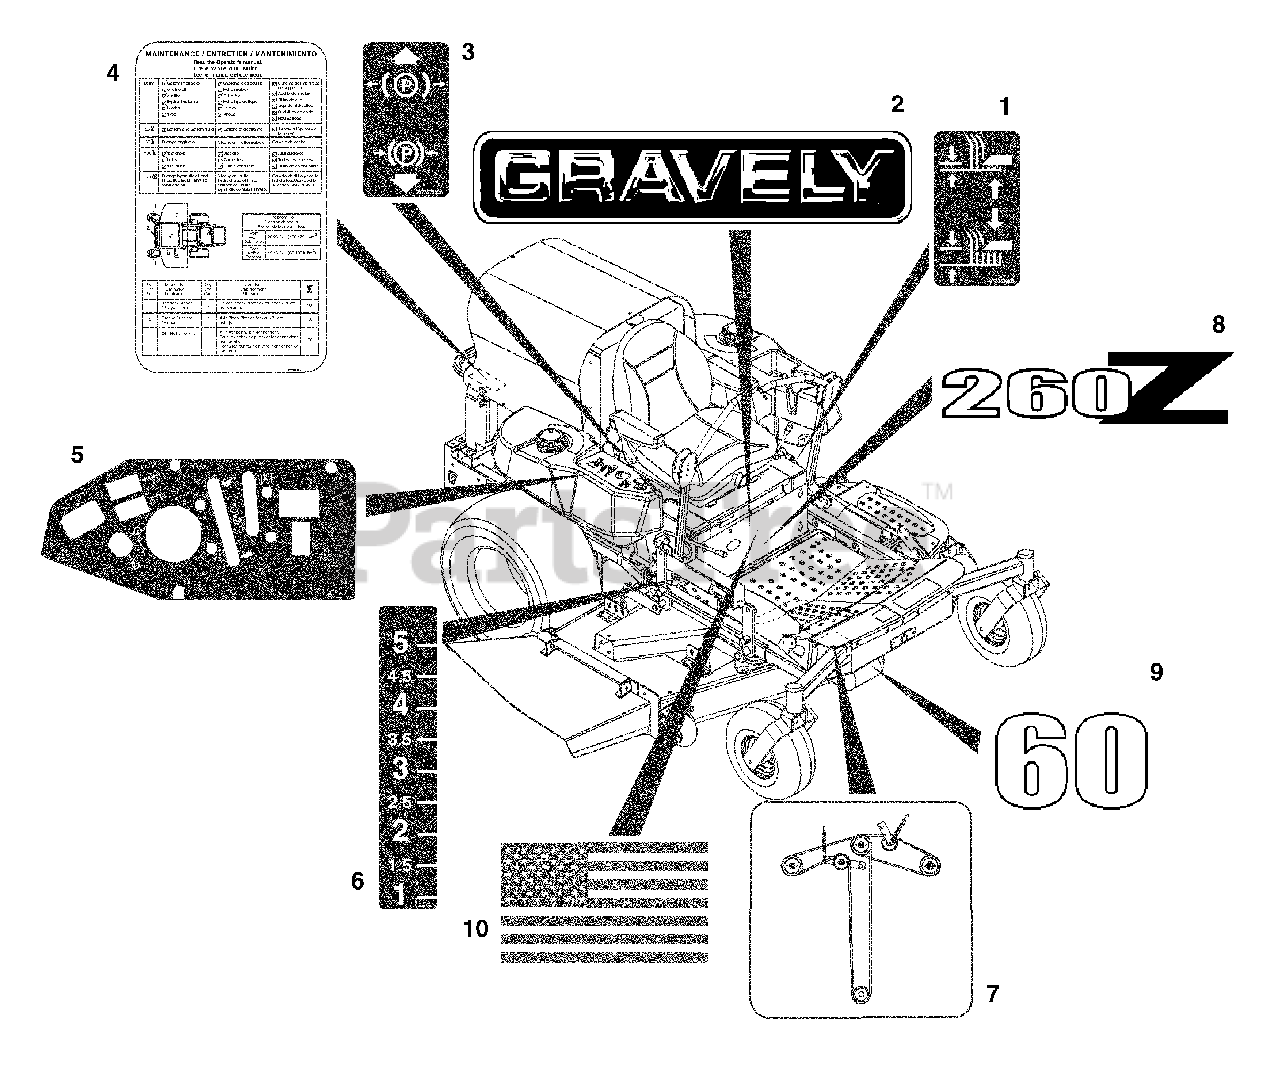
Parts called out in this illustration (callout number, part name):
1	Decal, Lift Lever
2	Decal, 15" Gravely Logo
3	Decal, Parking Brake Lever
4	Decal, Service Instructions
5	Decal, Gas Control Panel (036, 038, 309)
5	Decal, Diesel Control Panel (037, 039)
6	Decal, Height of Cut
7	Decal, Belt Diagram (036, 038, 309)
7	Decal, Belt Diagram (037, 039)
8	Decal, PM-260Z (036, 038, 309)
8	Decal, PM-272Z (037, 039)
9	Decal, 60 (036, 038, 309)
9	Decal, 72 (037, 039)
10	Decal, American Flag
